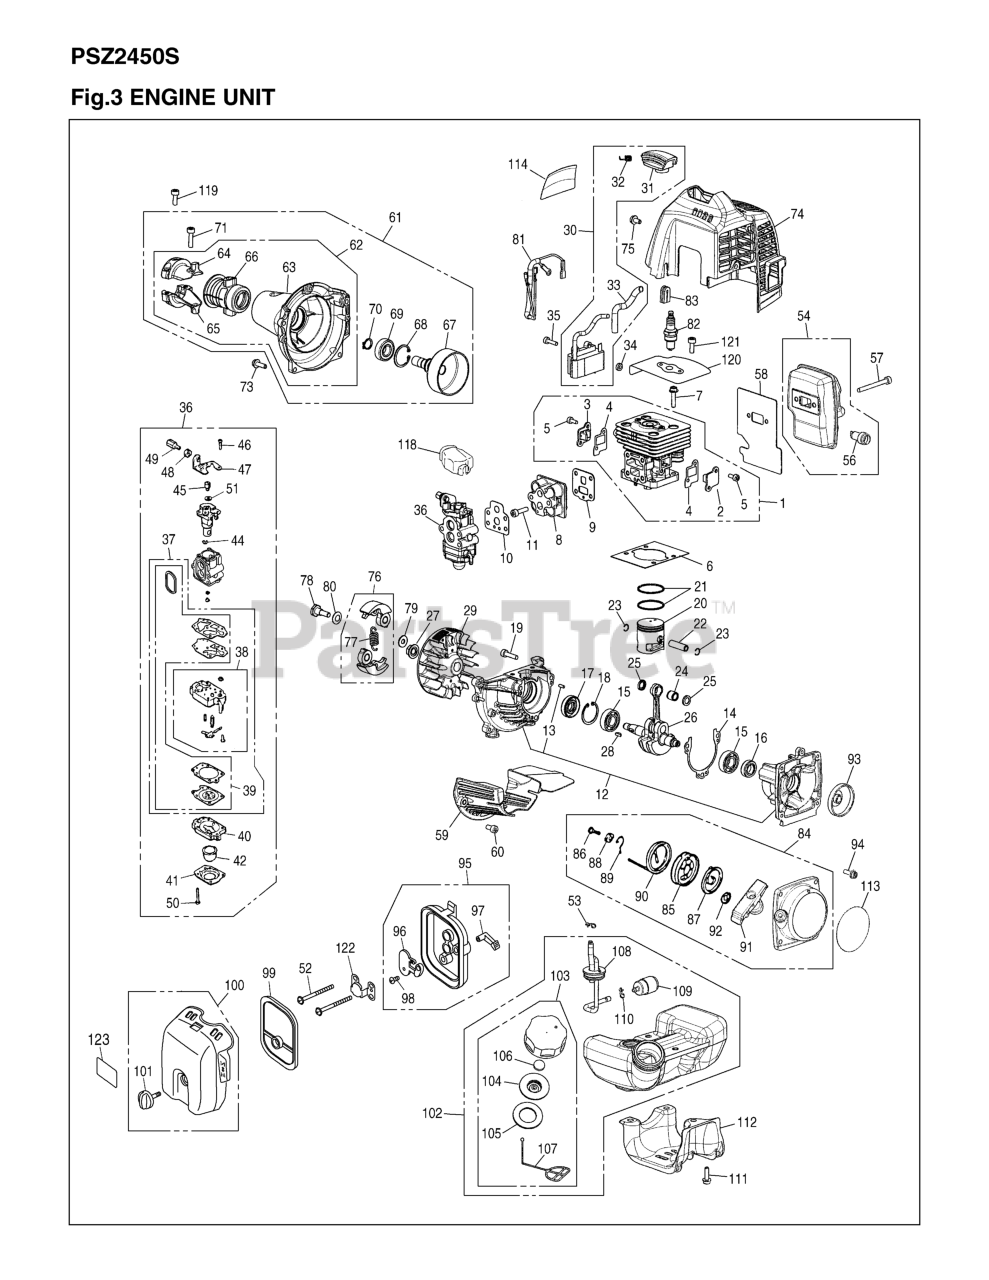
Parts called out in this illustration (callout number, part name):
1	CYLINDER COMP
2	COVER, TR-S
3	COVER, TR-F
4	GASKET, TR
5	BOLT
6	GASKET, BASE
7	BOLT
8	INSULATOR
9	GASKET
10	GASKET
11	BOLT, TORX
12	CRANKCASE COMP
13	PIN
14	GASKET, CASE
15	BEARING
16	SEAL
17	SEAL
18	RING
19	BOLT TORX
20	PISTON
21	RING
22	PIN
23	RING
24	BEARING
25	WASHER
26	CRANKSHAFT COMP
27	NUT
28	KEY
29	ROTOR
30	COIL ASSY
31	CAP
32	SPRING
33	TUBE
34	SPACER
35	BOLT TORX
36	CARBURETOR ASSY
37	REBUILD KIT
38	BODY ASSY
39	GASKET KIT
40	BODY
41	COVER
42	PUMP
44	RING
45	SWIVEL
46	SCREW
48	NUT
49	SCREW
50	SCREW
51	WASHER
52	BOLT TORX
53	CLIP
54	MUFFLER ASSY
56	ARRESTER
57	BOLT
58	GASKET, MUFF
59	PLATE
60	BOLT TORX
61	HOUSING ASSY
62	HOUSING COMP
64	BRACKET (A)
65	BRACKET (B)
66	CUSHION
67	DRUM
68	RING
69	BEARING
70	RING
71	BOLT TORX
73	BOLT
74	COVER, ENGINE
75	BOLT TORX
76	SHOE COMP
77	SPRING
78	BOLT
79	WASHER
80	WASHER
81	CORD COMP.
82	SPARK PLUG
83	GROMMET
84	RECOIL ASSY
85	REEL
86	SCREW
87	SPRING
88	COLLAR
89	ARM
90	ROPE
91	KNOB
92	PLATE
93	PULLEY
94	BOLT, TORX
95	CLEANER BODY ASSY
96	PLATE, CHOKE
97	LEVER
98	SCREW
99	ELEMENT
100	CLEANER COVER ASSY
101	CLEANER KNOB
102	TANK ASSY
103	CAP ASSY
104	HOLDER ASSY
105	PACKING
106	FILTER
107	STOPPER
108	PIPE COMP
109	FUEL FILTER (BLK SLEEVE)
110	CLIP
111	BOLT
112	GUARD, TANK
113	LABEL, RECOIL
114	LABEL, EMISSION
118	COVER
119	BOLT
120	PLATE
121	BOLT
